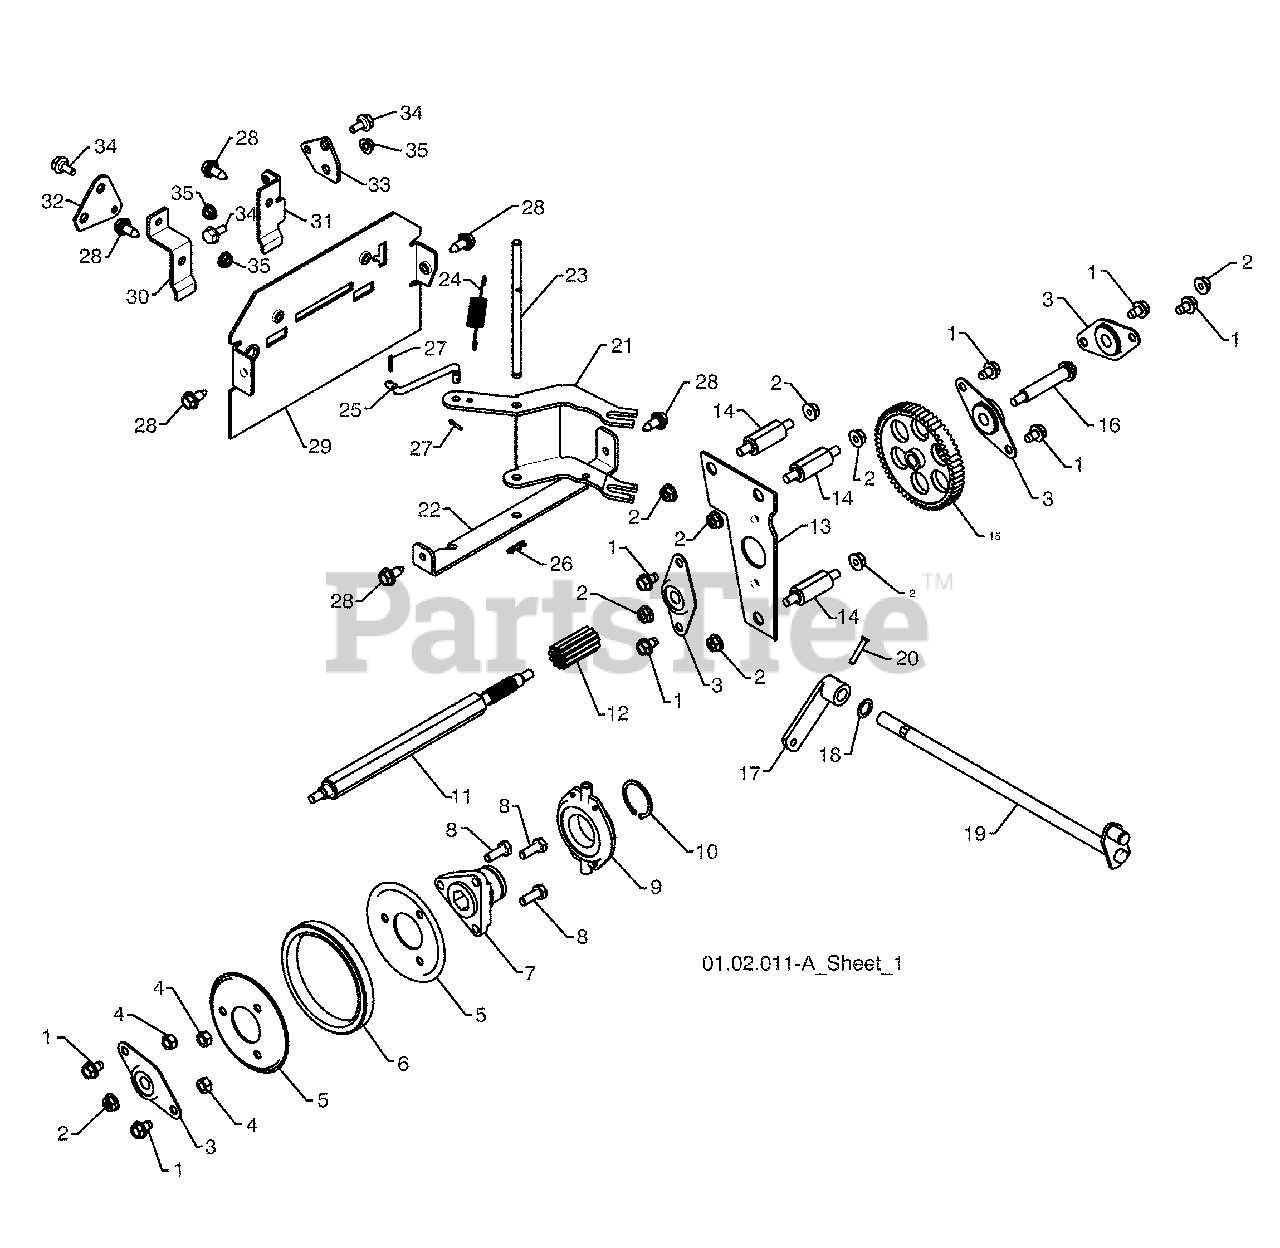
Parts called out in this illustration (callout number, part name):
1	BOLT 5/16-18 X .500
2	NUT 5/16-18
3	FLANGE BEARING
4	NUT 5/16-18
5	RUBBER WHEEL PLATE
6	RUBBER WHEEL RING
7	RUBBER WHEEL HUB
8	BOLT 5/16-18 X .875
9	TRUNNION BEARING ASSEMBLY
10	RETAINER
12	PINION GEAR
13	AUXILIARY PLATE
14	SPACER PLATE
15	INTERMEDIATE GEAR
16	AUXILIARY SHAFT
17	CONTROL ARM
19	CONTROL SHAFT ASSEMBLY
20	CLEVIS PIN
21	SHIFTER LEVER
22	PIVOT BRACKET
25	SHIFTER LINK
28	SCREW 5/16-18 x .750
29	REAR PLATE
30	SHIFTER PLATE BRACKET
31	CLUTCH PLATE BRACKET
32	SHIFTER PLATE
33	CLUTCH PLATE
34	SHOULDER BOLT 1/4-20 X .500
35	NUT 1/4-20
